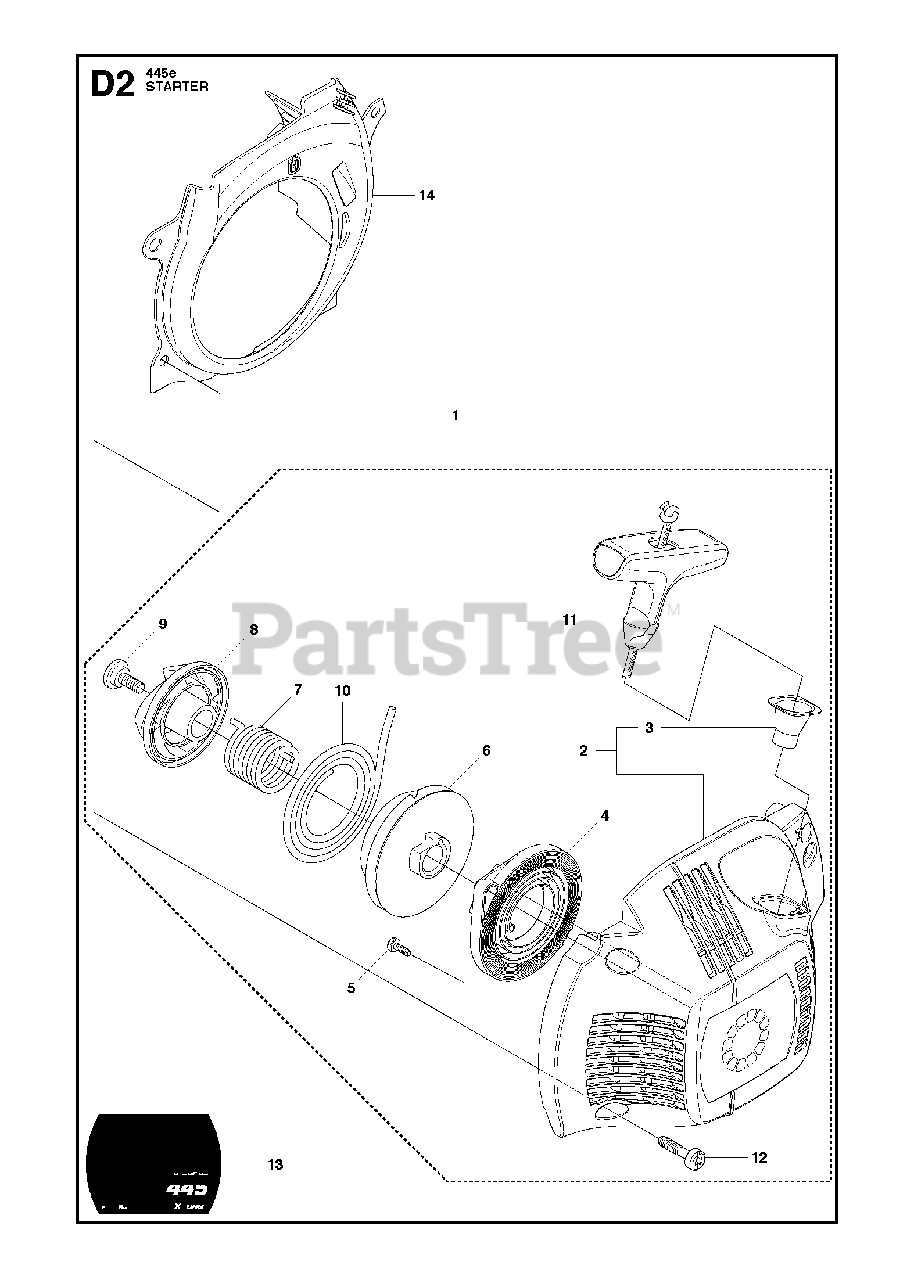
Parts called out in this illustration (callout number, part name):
1	STARTER ASSY
2	STARTER HOUSING
3	SLEEVE
4	SPRING CASSETTE ASSY
5	SCREW
6	STARTER PULLEY
7	SPRING
8	DRIVER
9	SCREW
10	STARTER ROPE
11	HANDLE
12	SCREW
14	COOLING AIR CONDUCTOR
